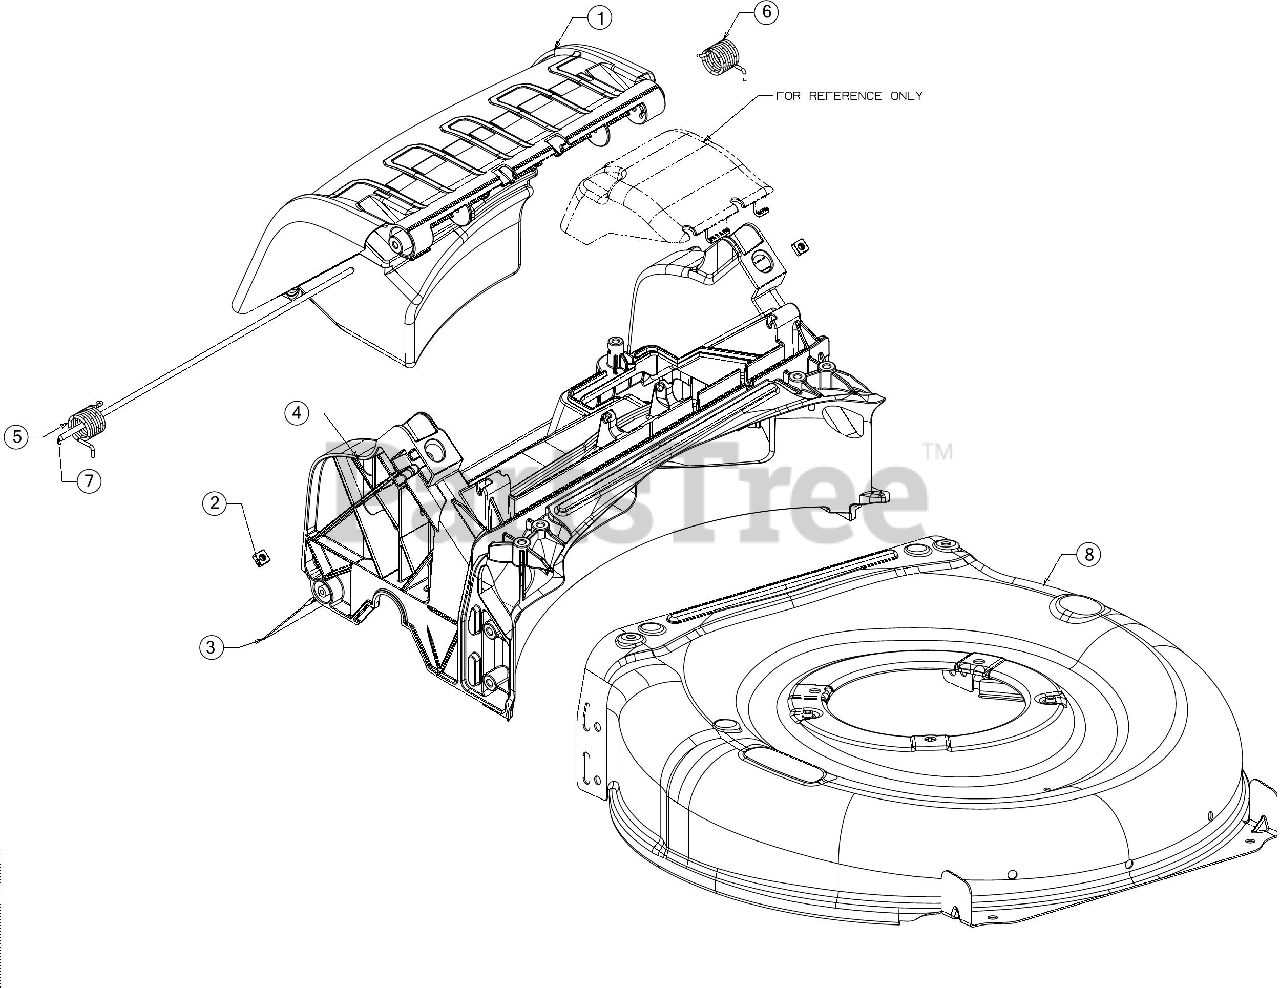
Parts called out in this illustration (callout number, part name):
2	SQUARE NUT 1/4-20
3	TRAILSHIELD
5	TORSION SPRING (RH)
6	TORSION SPRING (LH)
7	REAR DOOR PIVOT ROD
8	21" DECK (2N1)
